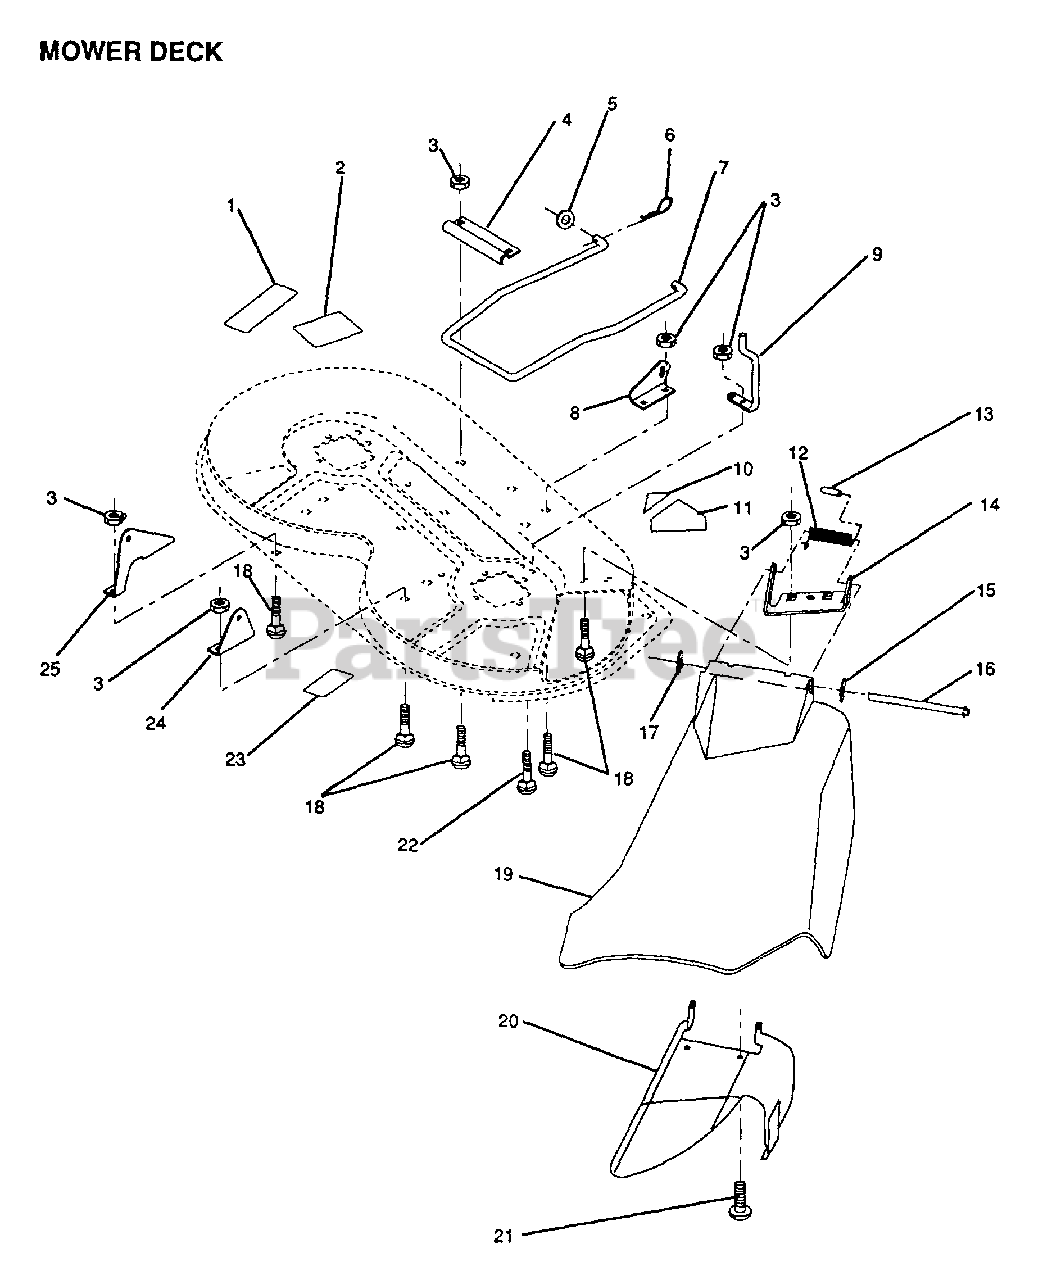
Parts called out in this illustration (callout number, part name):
1	DECAL YT
2	DECAL.LT
4	"BRKT,STAB LINK"
6	SPRING.RETAINER
7	STABILIZER MOWER
8	"BRKT,FRT LIFT RH"
9	"GUIDE,FRT MAN RH"
11	DECAL WARNING
12	SPRING TORSION
13	CAP-SLEEVE LT
15	WASHER
16	HINGE ROD
17	NUT PUSH M
18	BOLT
20	DEFL SUPT ASS'Y
21	SCREW PAN HD
22	BOLT
23	DECAL WARNING
24	"BRKT,REAR LIFT RH"
25	"BRKT,REAR LIFT LH"
